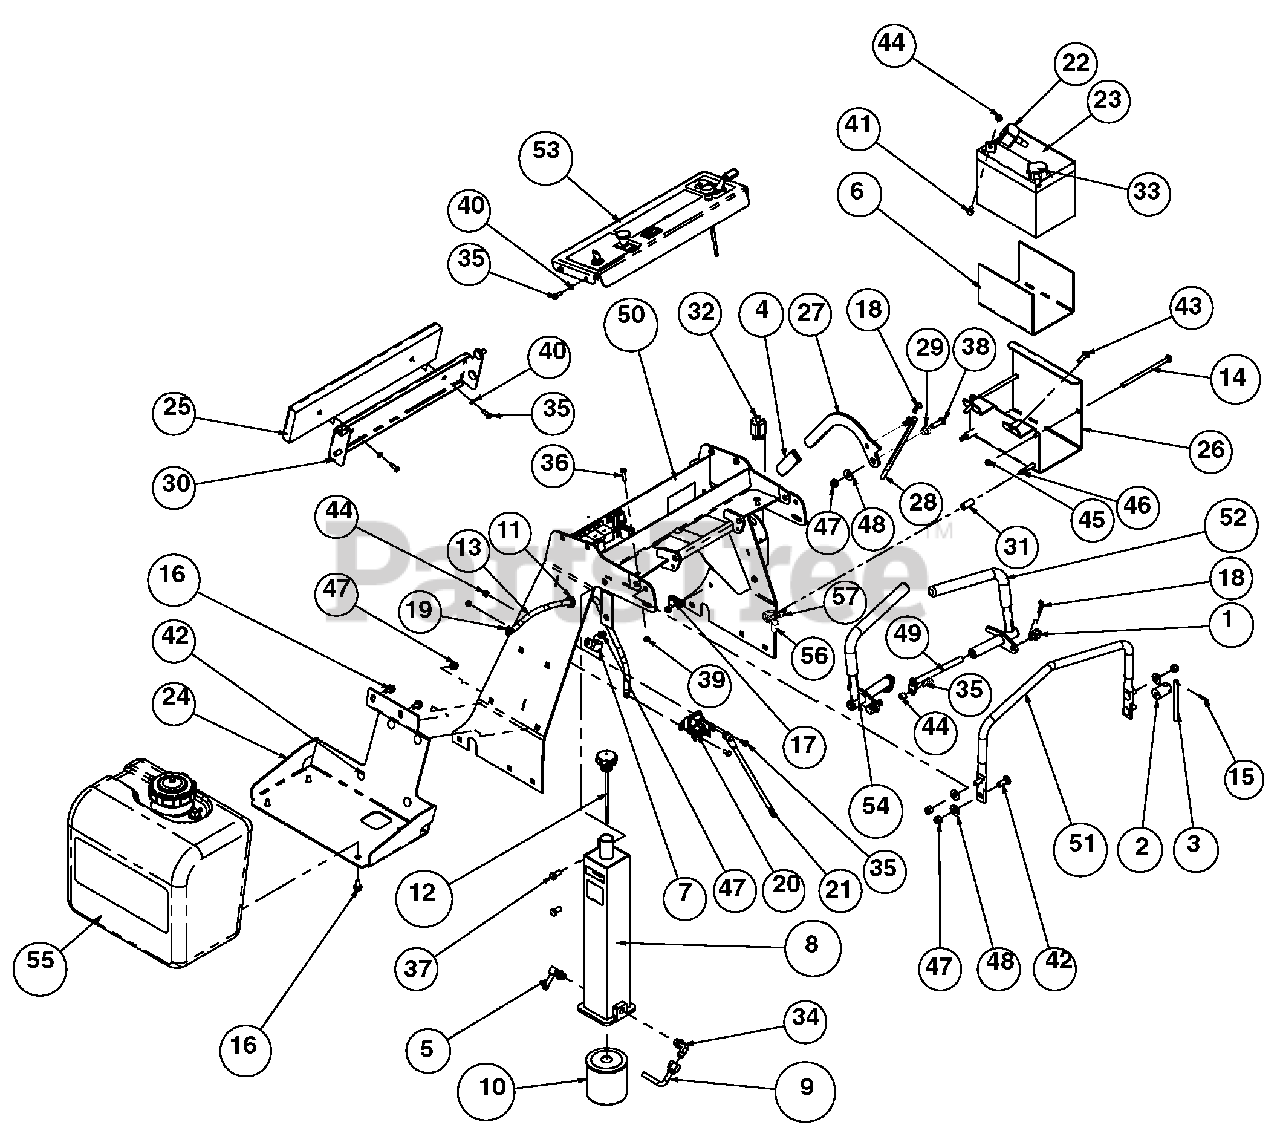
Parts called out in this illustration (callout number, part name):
1	Swivel Adjuster
2	Base, Lock Lever Y
3	Lever, Lock Y
4	Grip, PVC .250 x 1.00 x 3.63
5	Fitting, 90 9/16 MOR x 3/8 Hose
6	Strip, Battery Insulator
7	P-Clip, .750 Insulated
8	Reservoir, Hydraulic S/O
9	Elbow, Fitting
10	Filter, Oil
11	Clamp, Fuel Line
12	Cap, Filler Oil
13	Hose, 1/4" ID Low Perm Fuel 50
14	Bolt, 5/16-18 x 6.00 CRG 2 Y
15	Pin, Spring
16	Screw, Hex, FL,JDS123, M8 x 1.25 x 16
17	P-Clip, .500 Insulated
18	Pin, Hair .091 x 1.63 5/16-1/2 Y
19	Grommet, Round Rubber .625 x .19
20	Solenoid, 12 V Starter
21	Cable, 12" Starter
22	Cable, Battery Starter - 48"
23	Battery, 12V-U1-CCA270 Min
24	Bracket, Fuel Tank Mounting
25	Pad, Thigh
26	Tray, Battery
27	Lever, Brake
28	Link. Brake Y
29	Bushing, Brake Pivot Y
30	Weldment, Thigh Pad Bracket
31	Bushing, .364 x .540 x 1.250 Y
32	Switch, NO-NO-NC Grey Plunger
33	Cable, Battery Negative 30"
34	Fitting, 90 9/16 MOR x 9/16 MJIC
35	Bolt, 1/4-20 x .750 Hex 5 Y
36	Bolt, 1/4-20 x 1.00 Hex 5 Y
37	Bolt, 3/8-16 x .750 Hex 5 Y
38	Bolt, 3/8-16 x 1.25 Hex 5 Y
39	Nut, 1/4-20 Standard Hex Grade 5 Y
40	Washer, .250 Med. Spring Lock Y
41	Bolt, 1/4-20 x .625 WSH Y
42	Bolt, 3/8-16 x 1.00 CRG 5 SN Y
43	Bolt, 5/16-18 x 1.00 CRG 2 Y
44	Locknut, 1/4-20 Whiz Y
45	Locknut, 5/16-18 Nyloc Y
46	Bolt, 5/16-18 x 2.00 Round Head Square Neck 5 Y
47	Locknut, 3/8-16 Nyloc Y
48	Washer, .375 REG Flat Y
49	Weldment, Pin and Lock
50	Gravely Console With Decals
51	Handle, Support
52	LH Control Lever W/Grip
53	Assembly, Control Panel w/Decals (switches sold seperately)
54	RH Control Lever W/Grip
55	Tank, Fuel Assembly
56	P-Clip, .50 Insulated
57	Cable Tie .15 x 8.50
